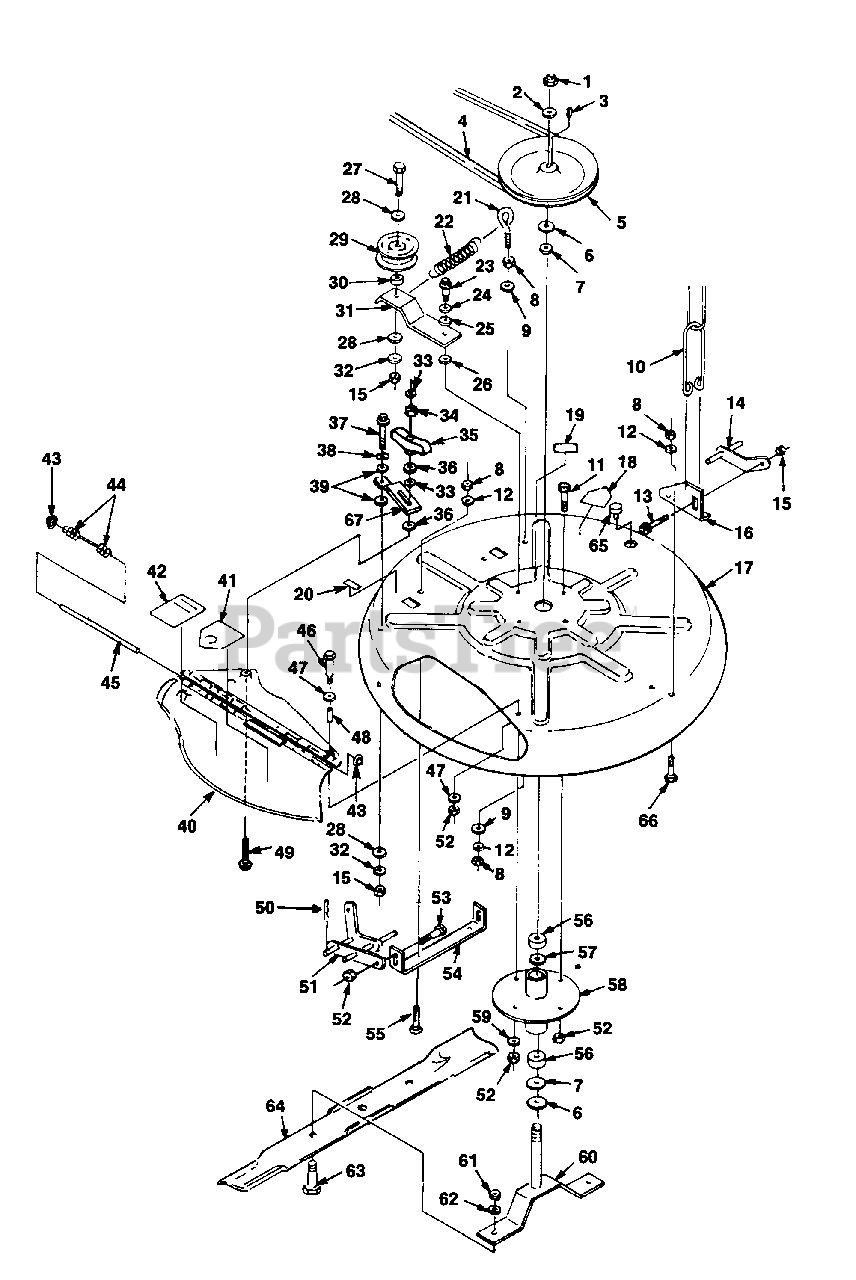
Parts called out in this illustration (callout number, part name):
2	WASHER- Flat (3/4")
8	Nut - hex 1/4-20 lock
9	WASHER- Plain (1/4")
10	LINK- Lower front lift
11	Superseded by UP03381
15	Nut (Hex Locking)
16	BRACKET- Front lift
19	DECAL- No step
20	DECAL- Warning
26	WASHER- Idler arm
28	WASHER- Flat (3/8")
32	Superseded by UP07435
33	NUT- Speed
35	HANDLE KNOB-TBO
36	Superseded by 84026
42	DECAL - Door Warning
44	SPRING- Torsion
47	Superseded by UP07173
49	BOLT- (1/4 x 1 1/4")
53	BOLT- 5/16-18
55	Superseded by 80052
56	BEARING TBO
58	HOUSING- Spindle
59	Superseded by UP03791
60	SPINDLE & ADAPTER
61	Nut (Hex Locking)
64	Superseded by UP06686
65	Superseded by JA994410
67	ARM- Pivot
